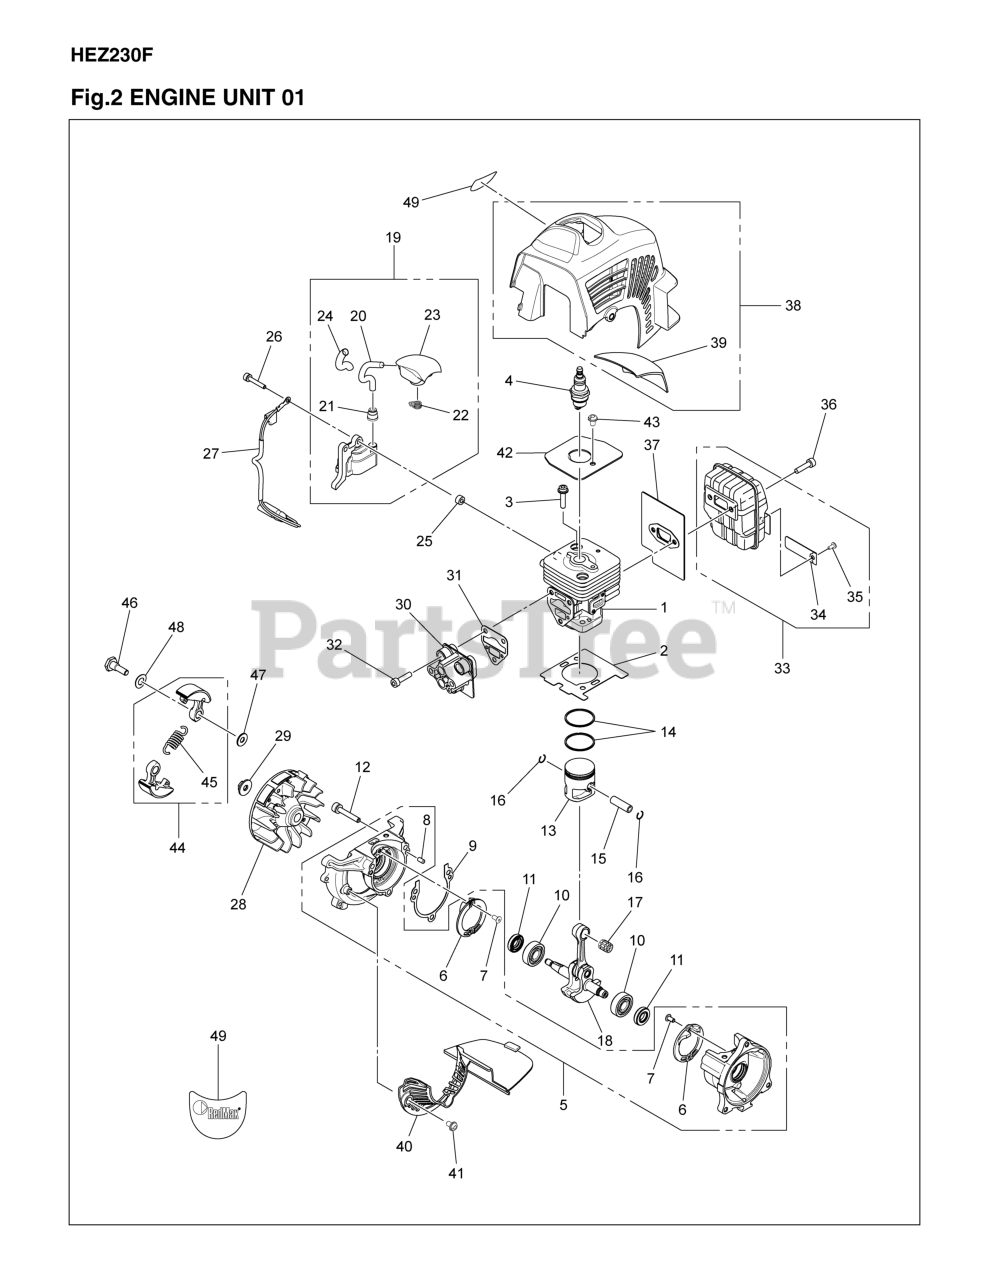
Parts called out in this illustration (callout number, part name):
1	CYLINDER COMP
2	GASKET BASE
3	BOLT
4	SPARK PLUG, BPMR8Y
5	CRANKCASE ASSY
6	COVER CASE
9	GASKET CASE
11	OIL SEAL 8488AA2000
14	RING PISTON
15	PIN.PISTON 8488B82600
18	CRANKSHAFT COMPLETE
19	IGNITION COIL ASSY
20	IGNITION CABLE
21	HUB CAP 848F6L71E0
23	SPARK PLUG CAP
24	TUBE (RPLS 263072210)
26	BOLT M4 X 25
27	SHORT CIRCUIT CABLE
28	FLYWHEEL
30	INSULATOR
33	MUFFLER ASSY
34	SPARK ARRESTER
35	SCREW CRPANT TYPE F ST4.2X9.5
37	GASKET MUFFLER
39	SHEET HEAT INSULATION TRZ230/B
40	PLATE MUFFLER
42	PLATE CYLINDER
44	CLUTCH ASSY
45	CLUTCH SPRING
49	DECAL BRAND
